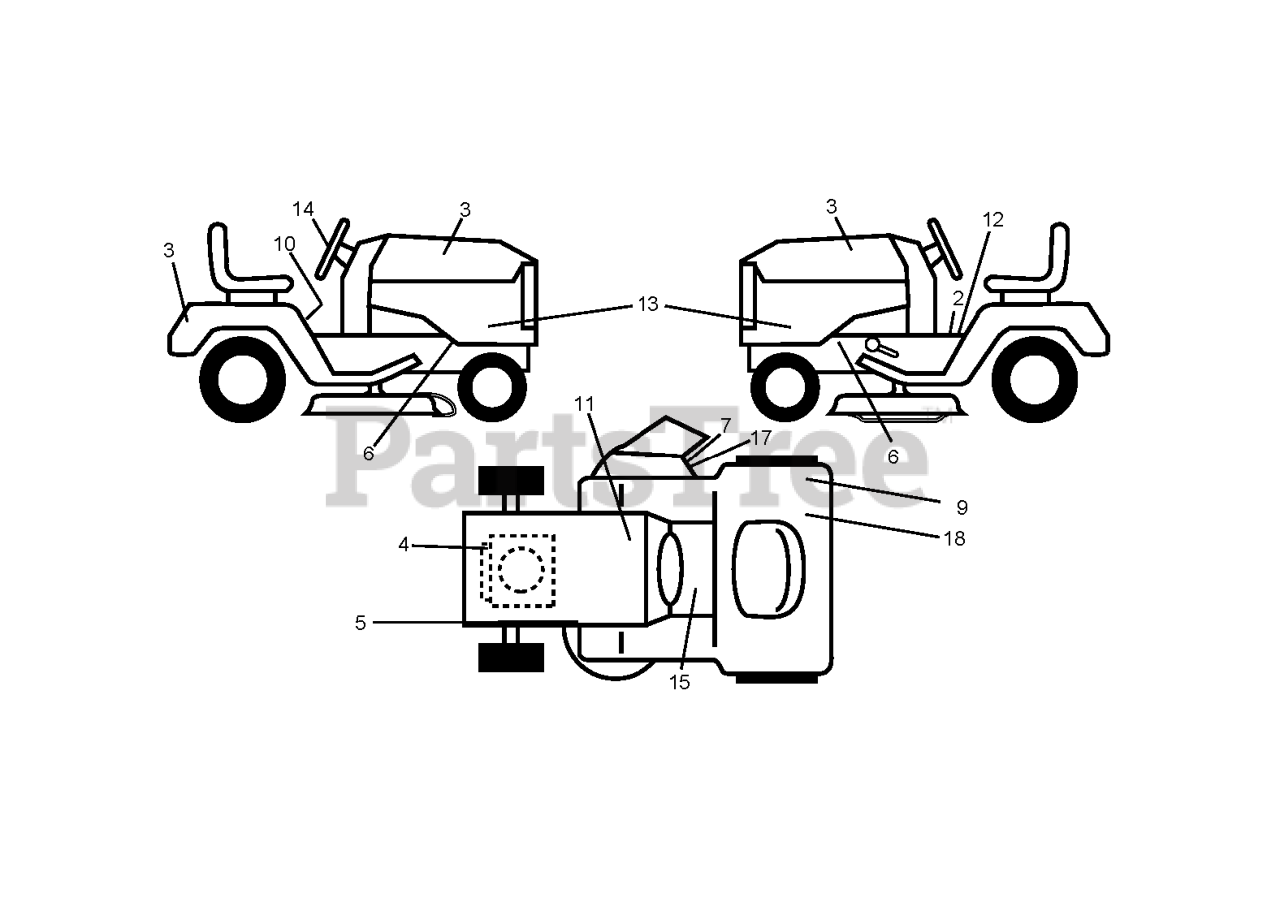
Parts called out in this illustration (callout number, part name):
2	DECAL PARK BRAKE
3	DECAL.HOOD.NAMELOGO.HUSQ
4	DECAL
5	DECAL V BELT SCHEMATIC
7	DECAL.INTERNATIONL.CUTFINGER
9	DECAL
10	LABEL
11	DECAL BTRY SYMBOLS
12	DECAL
14	DECAL.WHEEL.STRG.LGN.H
15	DECAL
17	DECAL, DEFLECT WARNING
18	DECAL 80 DBA
